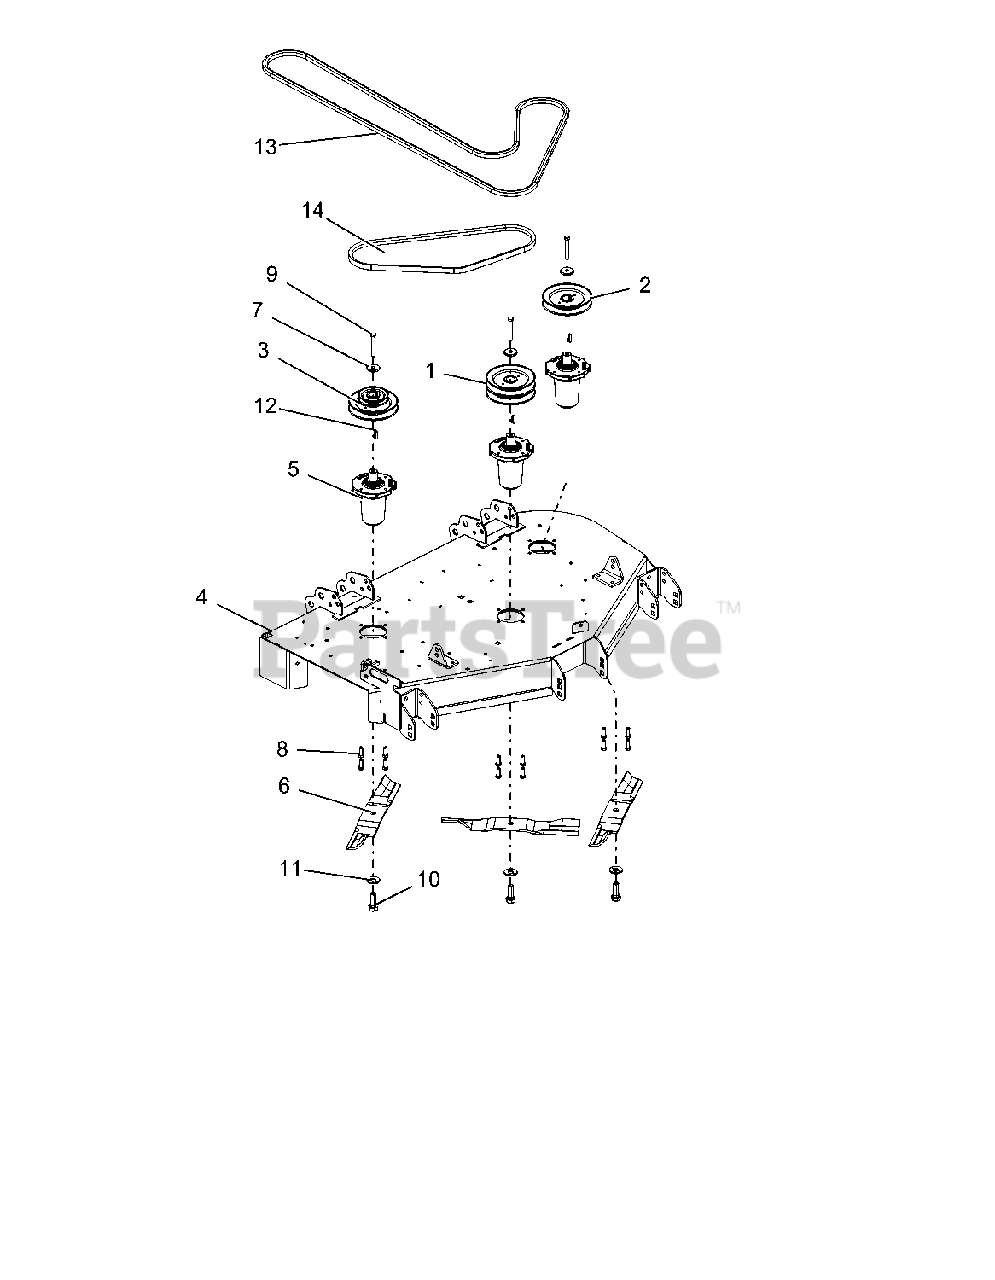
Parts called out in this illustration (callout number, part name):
1	PULLEY, DOUBLE-1" ID X 5.75" OD-BLACK
2	PULLEY, V - 1" ID X 5.75" OD-BLACK
3	PULLEY, DBL -1"IDX5.75"&3.50"OD-BLACK
4	WLDMT, DECK 44" SIDE DISCH-RED
5	ASM, SPINDLE - G3500
6	BLADE, 16.19" MOWER (HI-LIFT)
7	RETAINER, SHEAVE SPINDLE
8	BLT-HEX .38-16X1.00 GR5 YWZC EP30
9	BLT-HEX .38-16X2.75 GR8 YWZC
10	BLT, HEX .62-18X1.75 GR8 YWZC
11	WSHR, BLVL .63X1.625X.14
12	KEY-SQ .250X.250X1.00 RC 40-50
13	HEX BELT, BB WRAPPED
14	V-BELT, B-RAW EDGE COGGED
